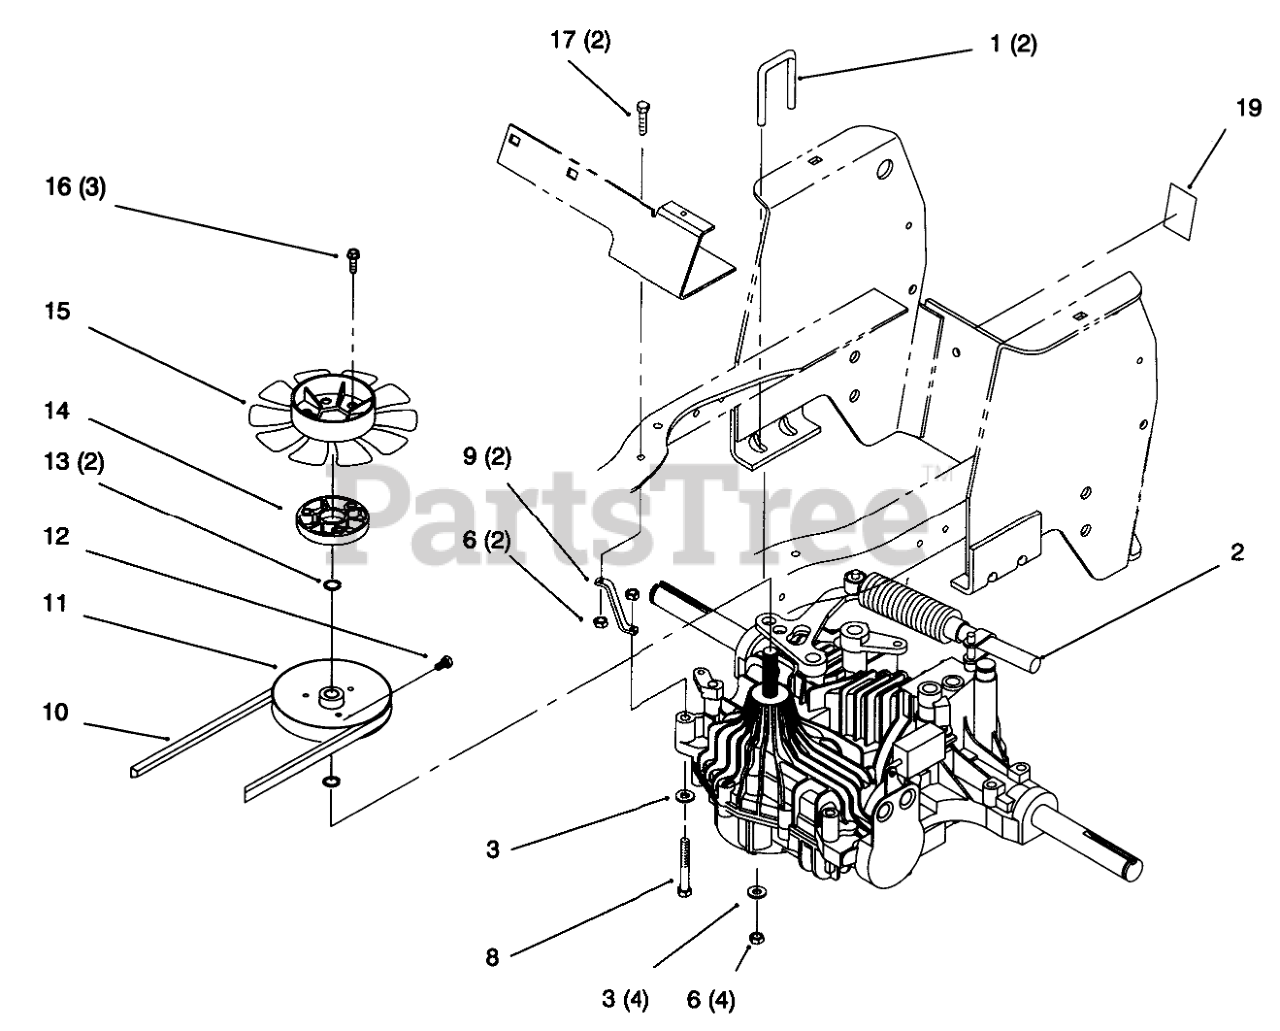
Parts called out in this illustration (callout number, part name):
1	U-Bolt (Only On: 72043, 72063, 72103)
2	Transaxle-Tuff Torq K61 (Only On: 72043, 72063, 72103)
3	Washer-Flat (Only On: 72043, 72063, 72103)
6	Nut-Lock (Only On: 72043, 72063, 72103)
8	Screw HH (Only On: 72043, 72063, 72103)
9	Strap-Torque (Only On: 72043, 72063, 72103)
10	Belt-Hydro (Only On: 72043, 72063, 72103)
11	Pulley (Only On: 72043, 72063, 72103)
12	Screw-Set (Only On: 72043, 72063, 72103)
13	Snap Ring (Only On: 72043, 72063, 72103)
14	Spacer-Fan (Only On: 72043, 72063, 72103)
15	Fan (Only On: 72043, 72063, 72103)
16	Screw-HH (Only On: 72043, 72063, 72103)
17	Screw-HH (Only On: 72043, 72063, 72103)
19	Decal-Hydro Valve (Only On: 72043)
19	Decal-Bypass (Only On: 72063, 72103)
